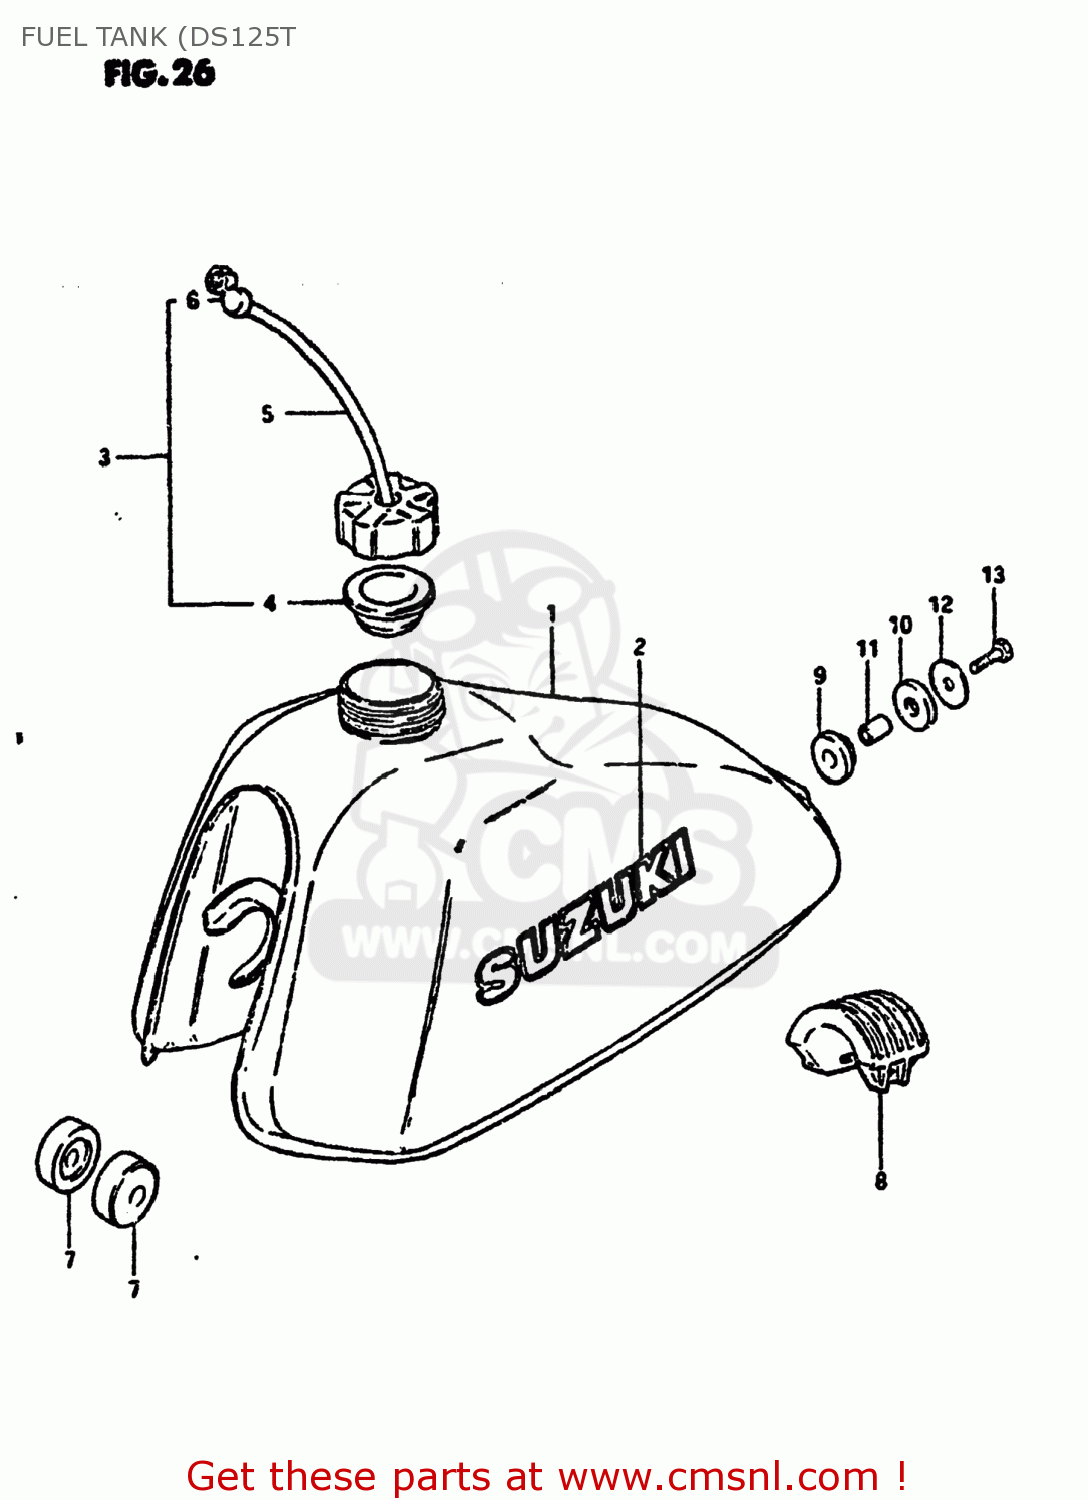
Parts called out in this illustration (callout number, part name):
1	TANK ASSEMBLY,FUEL
2	EMBLEM,FUEL TANK(WHITE)
3	CAP SET,FUEL TANK
4	GASKET,FUEL TANK CAP (NAS)
5	HOSE
6	CLAMP,FUEL TANK BREATHER HOSE
7	CUSHION
8	CUSHION,FUEL TANK
9	CUSHION
10	CUSHION
11	SPACER(8.5X12X19)
12	WASHER (8.5X29X1.6)
13	BOLT (8X30)
